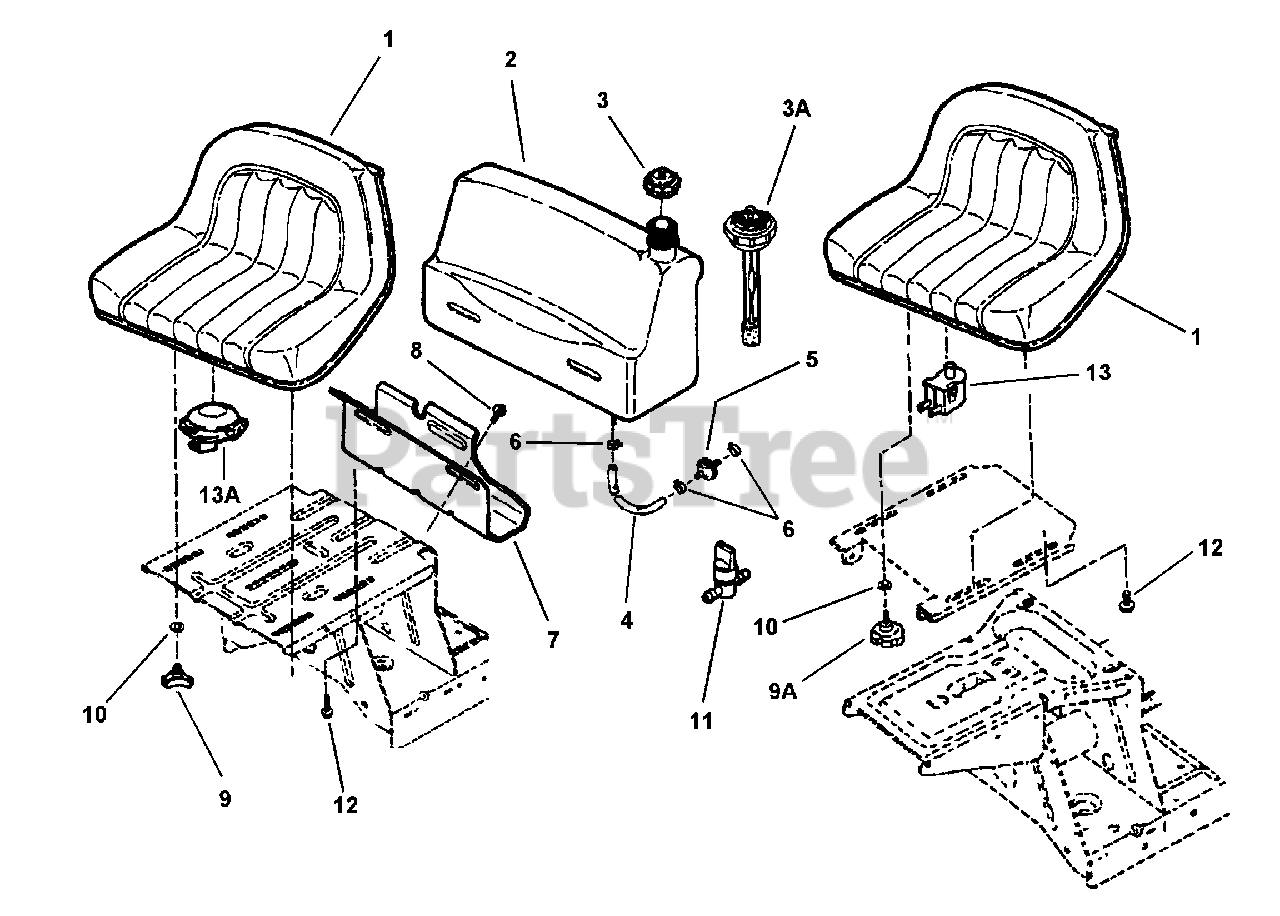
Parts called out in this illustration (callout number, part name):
1	SEAT, Operator (DeLuxe Back)
2	ASSEMBLY, Fuel Tank
3	CAP, Fuel Tank
3A	CAP, Fuel Tank (With Gauge)
4	HOSE, Fuel (8-1/2" Long)
5	FILTER, Fuel (In-Line)
6	CLAMP, Fuel Line
7	BRACKET, Fuel Tank (Rear)
8	SCREW, 5/16-18 x 5/8" Pan Head Self-Tap (Torx #T-40)
9	KNOB, Seat Adjusting
9A	KNOB, Hinged Seat
10	SPACER, 5/16
11	VALVE, Fuel Shut-Off (Accessory)
12	BOLT, 5/16-18 x 1/2" Hex Flange Lock w/Nylon Patch
13	SWITCH, Seat
13A	SWITCH, Seat
